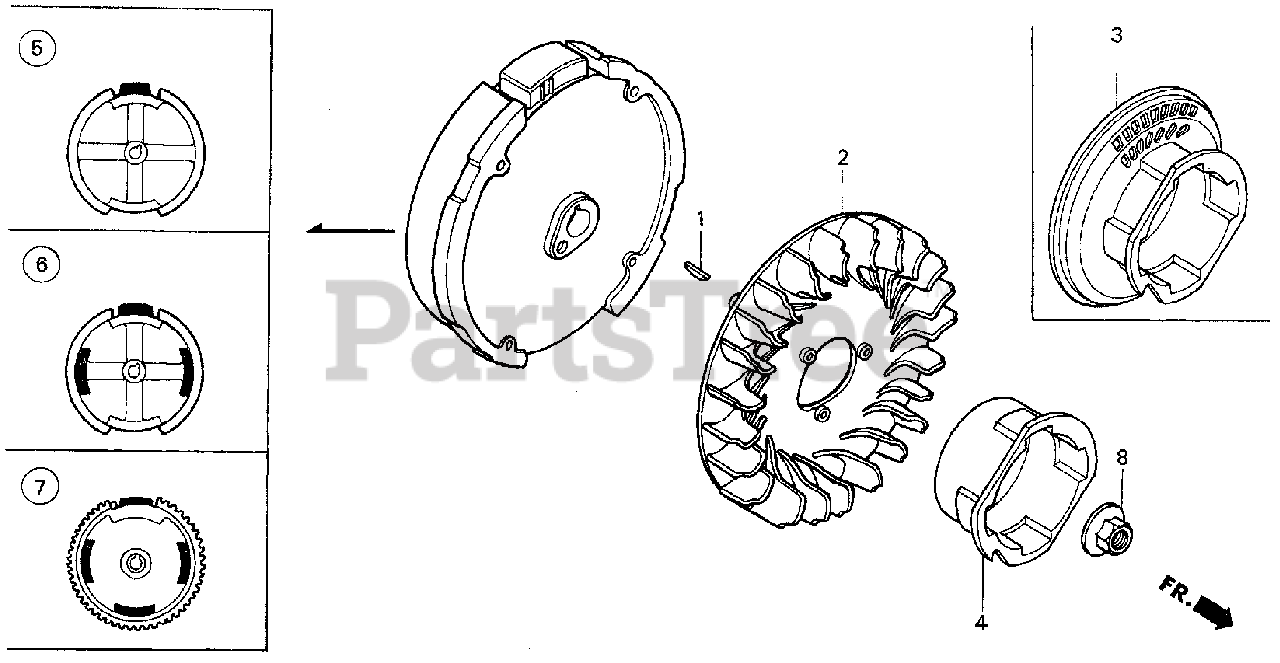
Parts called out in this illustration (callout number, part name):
1	KEY, SPECIAL WOODRUFF (25X18)
2	FAN, COOLING
4	PULLEY, STARTER
7	FLYWHEEL (SELF STARTER-7A)
8	NUT, SPECIAL (14MM)
